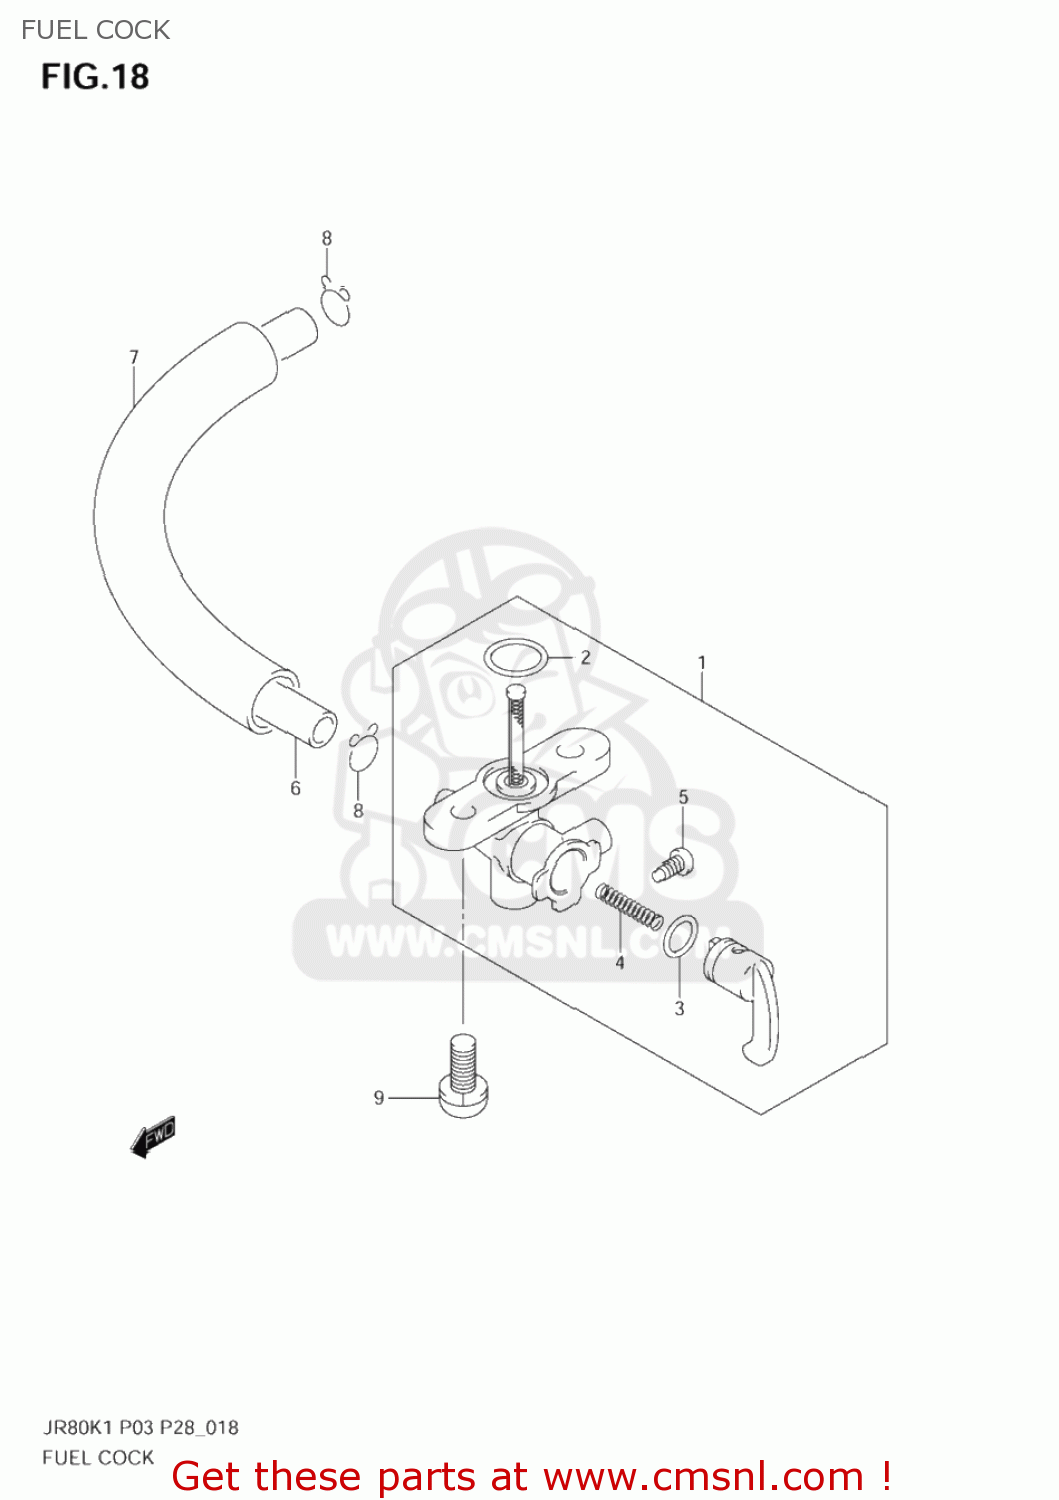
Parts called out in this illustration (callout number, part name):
1	COCK ASSY,FUEL
2	O RING
3	O RING,LEVER
4	SPRING
5	SCREW
6	HOSE(5X10X600)
7	PROTECTOR(14.5X15.5X600)
8	CLIP
9	SCREW
